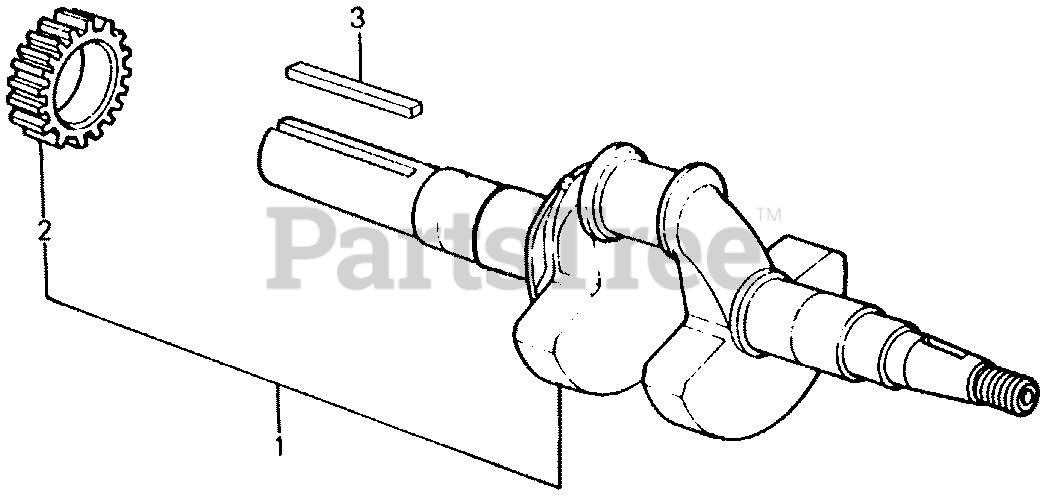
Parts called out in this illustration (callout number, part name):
1	CRANKSHAFT (S-TYPE)
2	GEAR, TIMING
3	KEY (5X5X33)
